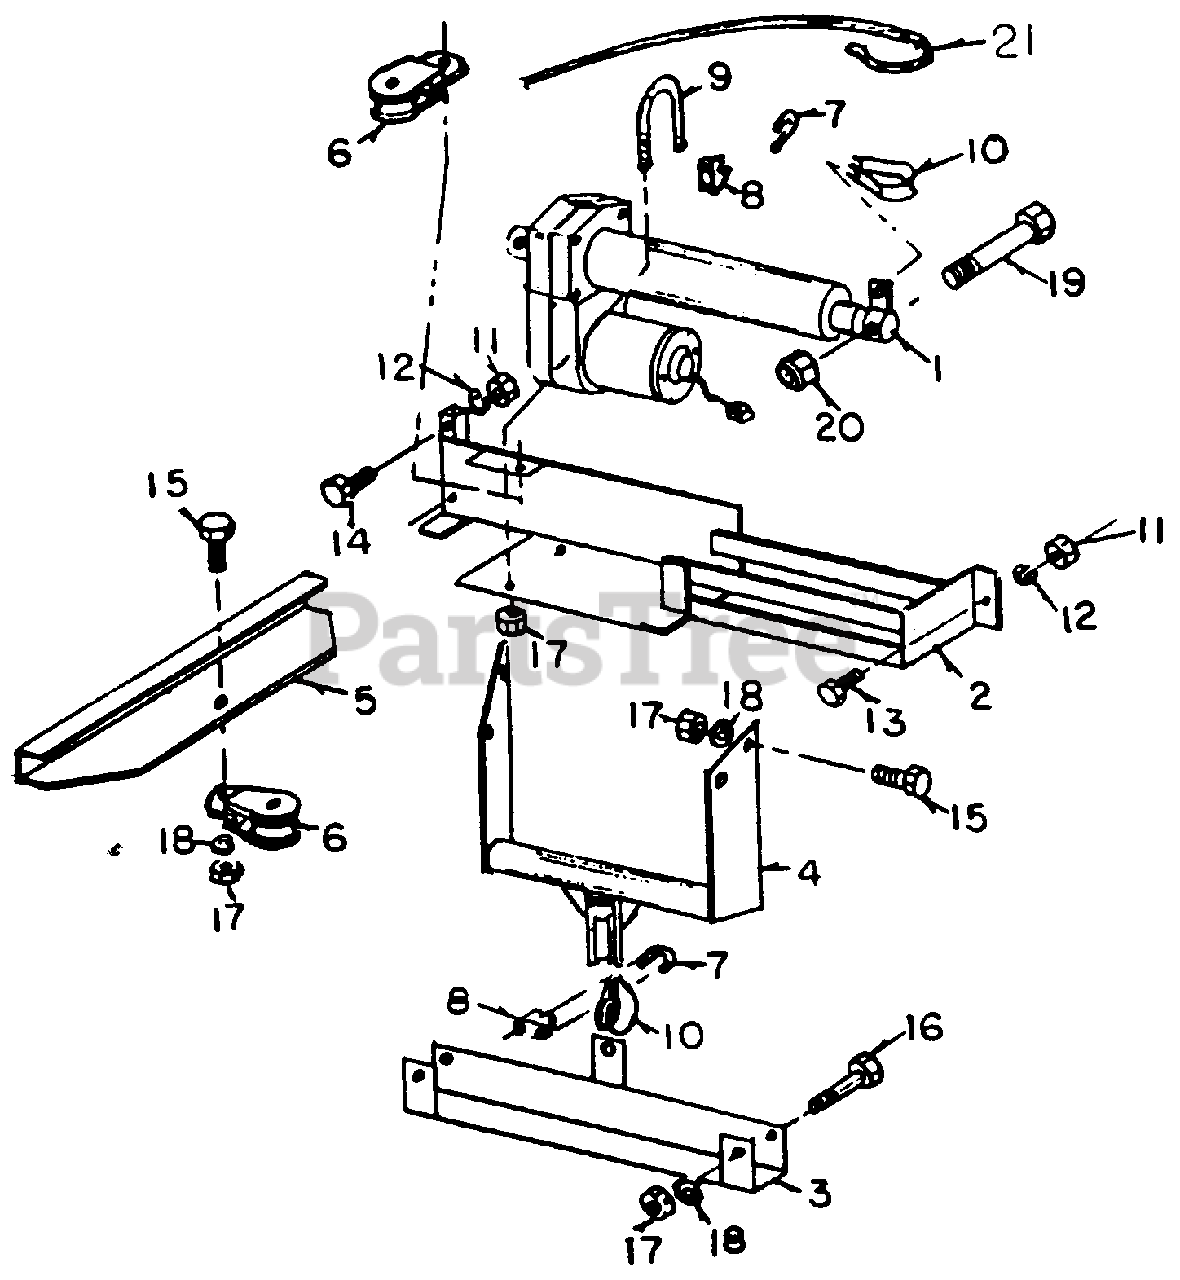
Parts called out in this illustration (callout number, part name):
1	Actuator
2	Actuator Mount
3	Deck Lift Adapter
4	Cable Mount, Nose
5	Cable Mount Side
6	Cable Pulley
7	U-bolt
8	Cable Clamp
9	U-bolt, Actuator
10	Cable Thimble
11	Hex Nut, 1/4-20
12	Lockwasher, 1/4"
13	Hex Capscrew, 114-20 x 3/4", GRS
14	Hex Capscrew, 1/4-20 x 1", GRS
15	Hex Capscrew, 5/16-18 x 1", GRS
16	Hex Capscrew, 5/16-18 x 2", GRS
17	Hex Nut, 5/16-18
18	Lockwasher, 5/16"
19	Actuator Bolt
20	Hex Locknut, 1/2-13
21	Cable, 3/16" x 64"
